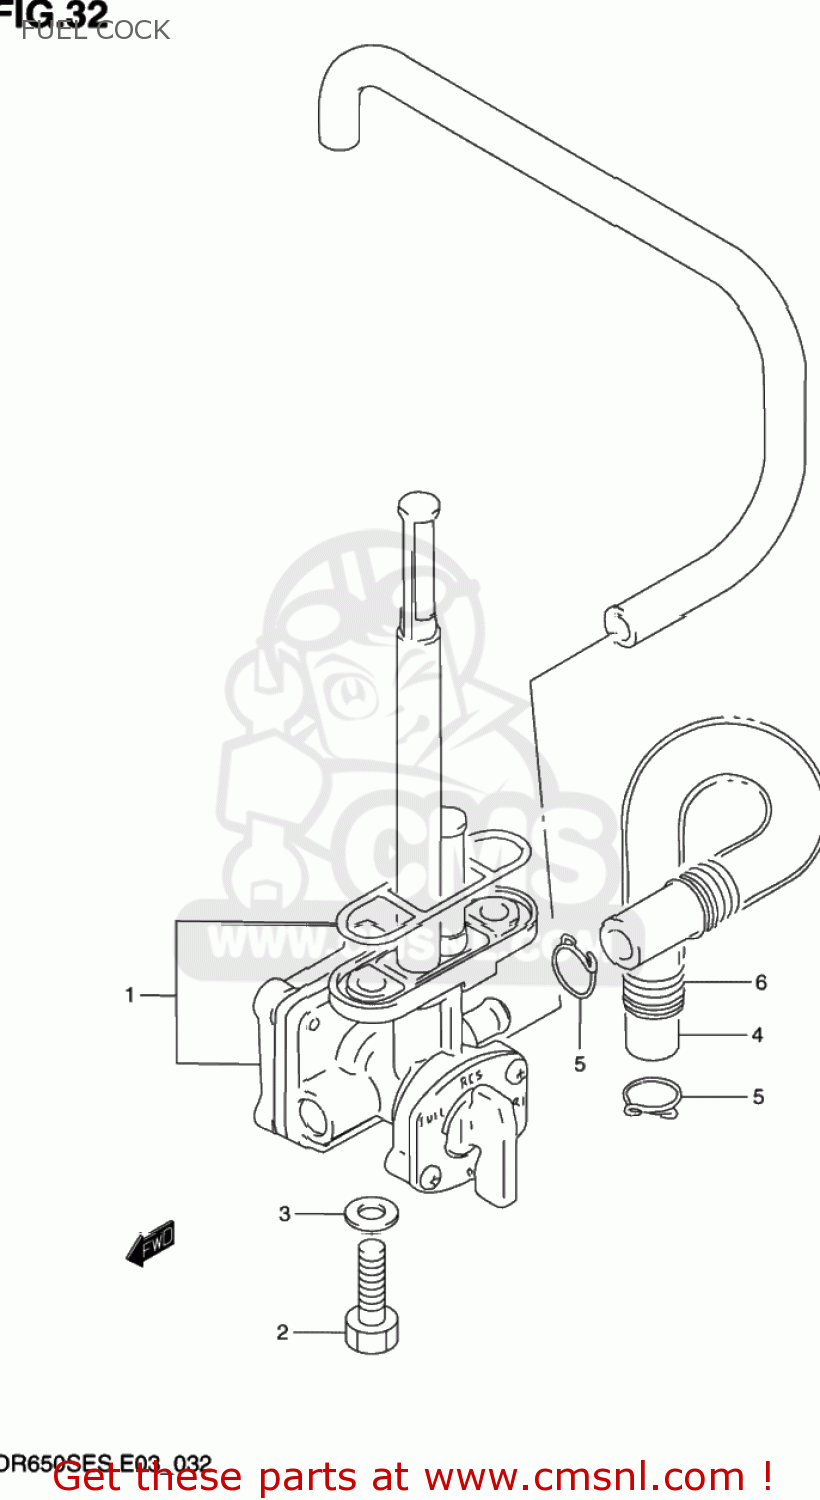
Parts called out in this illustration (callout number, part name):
1	COCK ASSY,FUEL
2	BOLT(6X20)
3	GASKET(6.4X11.5X0.8) (NAS)
4	HOSE(7X11X600)
5	CLIP
6	SPRING
